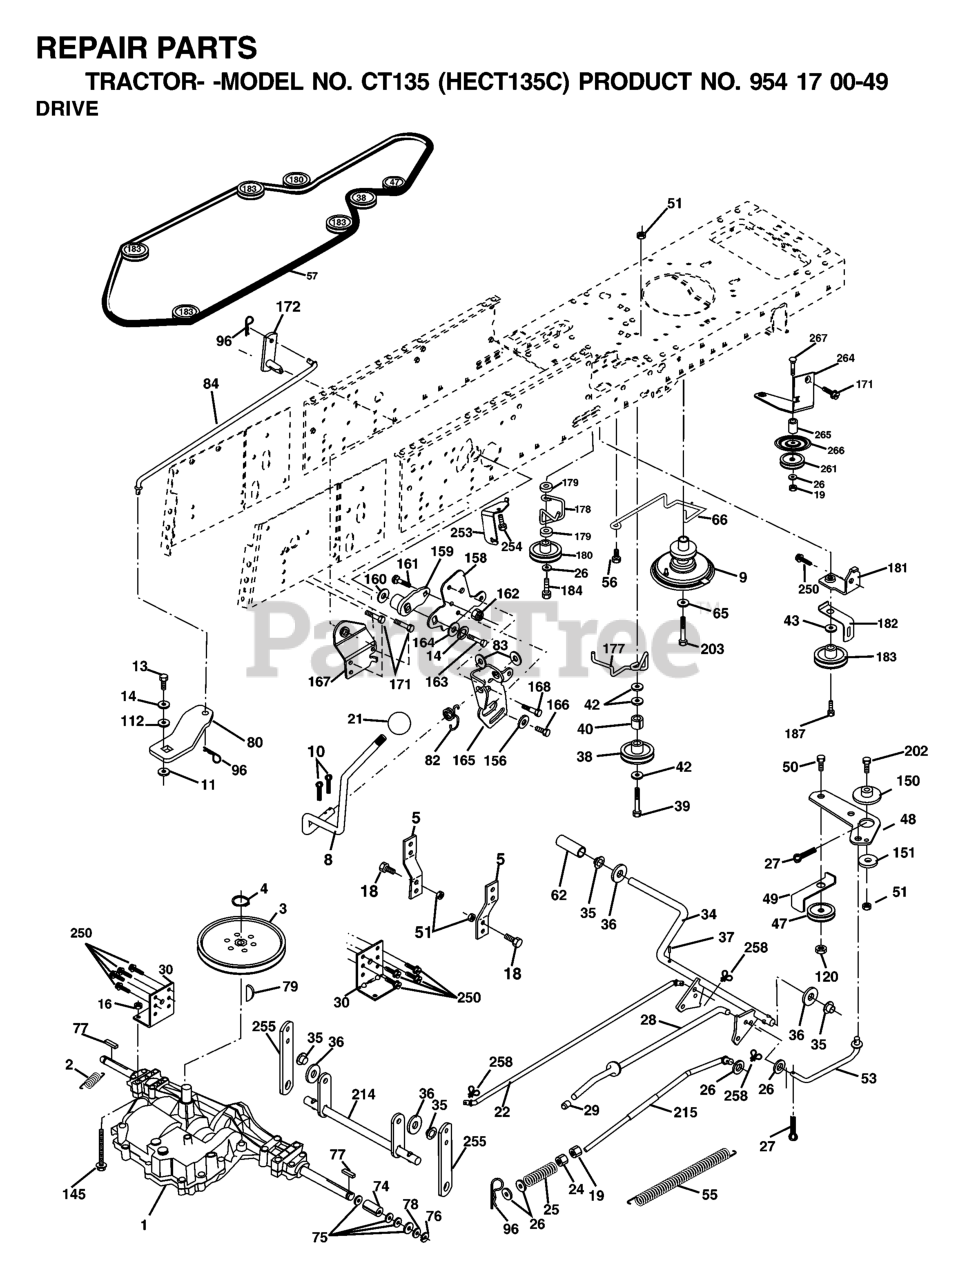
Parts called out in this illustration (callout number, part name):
2	SPRING,BRAKE RETURN
3	PULLEY
4	RETAINING RING LT
5	STRAP TORQUE
8	ROD.SHIFT.FENDER.ADJ.LT.CRD
9	RP CLUTCH.NORAM.2002
10	PIN COTTER
11	WASH-SHFT PLT LT
13	BOLT 1/4-28X3/4
14	LOCKWASHER
16	NUT.71038.31-18.HEX.NYLOCK
19	NUT
21	KNOB.DUCKHEAD.1/2
22	ROD
24	NUT
25	SPRING ROD LT
26	WASHER
27	COTTER PIN
28	ROD, PARKING BRAKE
29	PLUNGER CAP
30	BRKT, MOUNT TRNSAXLE
34	SHAFT, FOOT PEDAL
35	BEARING.NYLON
37	DRIVE PIN
38	PULLEY.FLAT
42	WASHER
47	IDLER PULLEY
48	BELLCRANK, CLUTCH
49	RETAIN BELT
50	BOLT
53	LINK, CLUTCH LT
55	SPRING, RETURN LT
56	SCREW.3/8-16
57	V-BELT.KEV.111"
62	COVER, PEDAL (1 2)
65	LOCKWASHER
66	KEEPER BELT ENGINE
74	SPACER AXLE
77	SQUARE KEY
79	KEY STD (1373) DANA
82	SHIFT SPRING
83	WASHER
96	RETAINER M
120	NUT LOCK FLG 3/8-16 UNC
150	BUSHING.BELLCRANK.GRD.DR
151	WASHER 12/32X2X10GA
156	WASHER.SRRTD.5/16
158	BRACKET
159	HUB
160	Washer 29/32 x 1 - 1/4 x 16 Ga.
161	BOLT
162	NUT.CROWNLOCK.1/4
164	Washer 5/8 x .281 x 10 Ga.
165	RP BRACKET
167	BRACKET.SUPT.SHIFT.CRD
168	BOLT.SHOULDER.5/16-18X
172	SHAFT
180	PULLEY.FLAT.IDLER
181	BRACKET
182	KEEPER BELT
184	SCREW.HXWSH.3/8
187	BOLT.5/16-18X1.25
202	BOLT
203	BOLT.HEX.7/16-20 X 5
214	LEVER
250	SCREW 3/8-16X3/4
254	SCREW THDROL 3/8-16 X 1-1/2
255	SHAFT
258	CLIP RETAINER
261	FLAT IDLER PULLEY
265	SPACER IDLER
266	PROTECTOR
267	BOLT.SS.CARR.3/8-16X3.25.GR5
